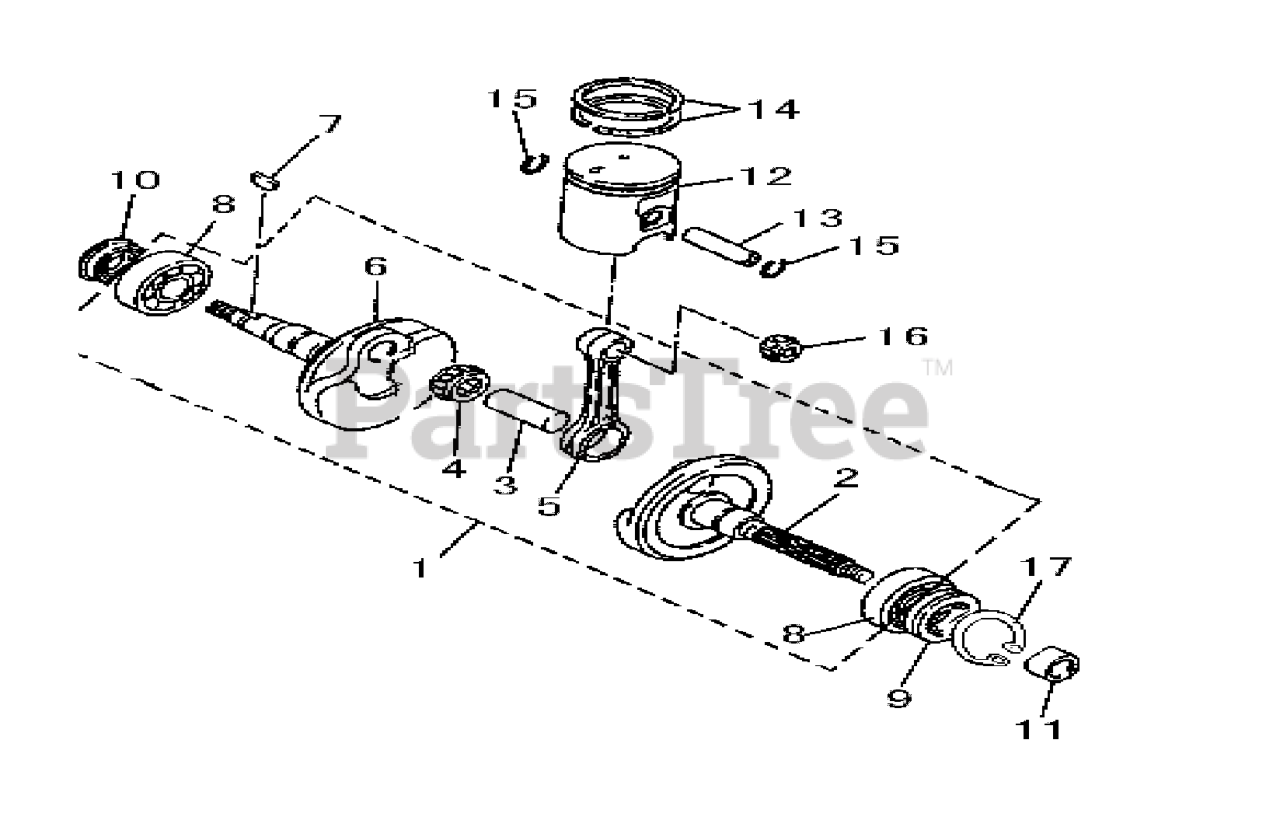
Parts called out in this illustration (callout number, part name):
1	CRANKSHAFT, ASSY
2	CRANKSHAFT, LH
3	CRANK PIN
4	NEEDLE BEARING
5	CONNECTING SHAFT
6	CRANKSHAFT, RH
7	WOODRUFF KEY
8	NEEDLE BEARING
9	OIL SEAL
10	OIL SEAL ASSY
12	PISTON ASSY
13	PISTON PIN
14	PISTON RING ASSY
15	CIRCLIP
16	NEEDLE BEARING
17	CIRCLIP
